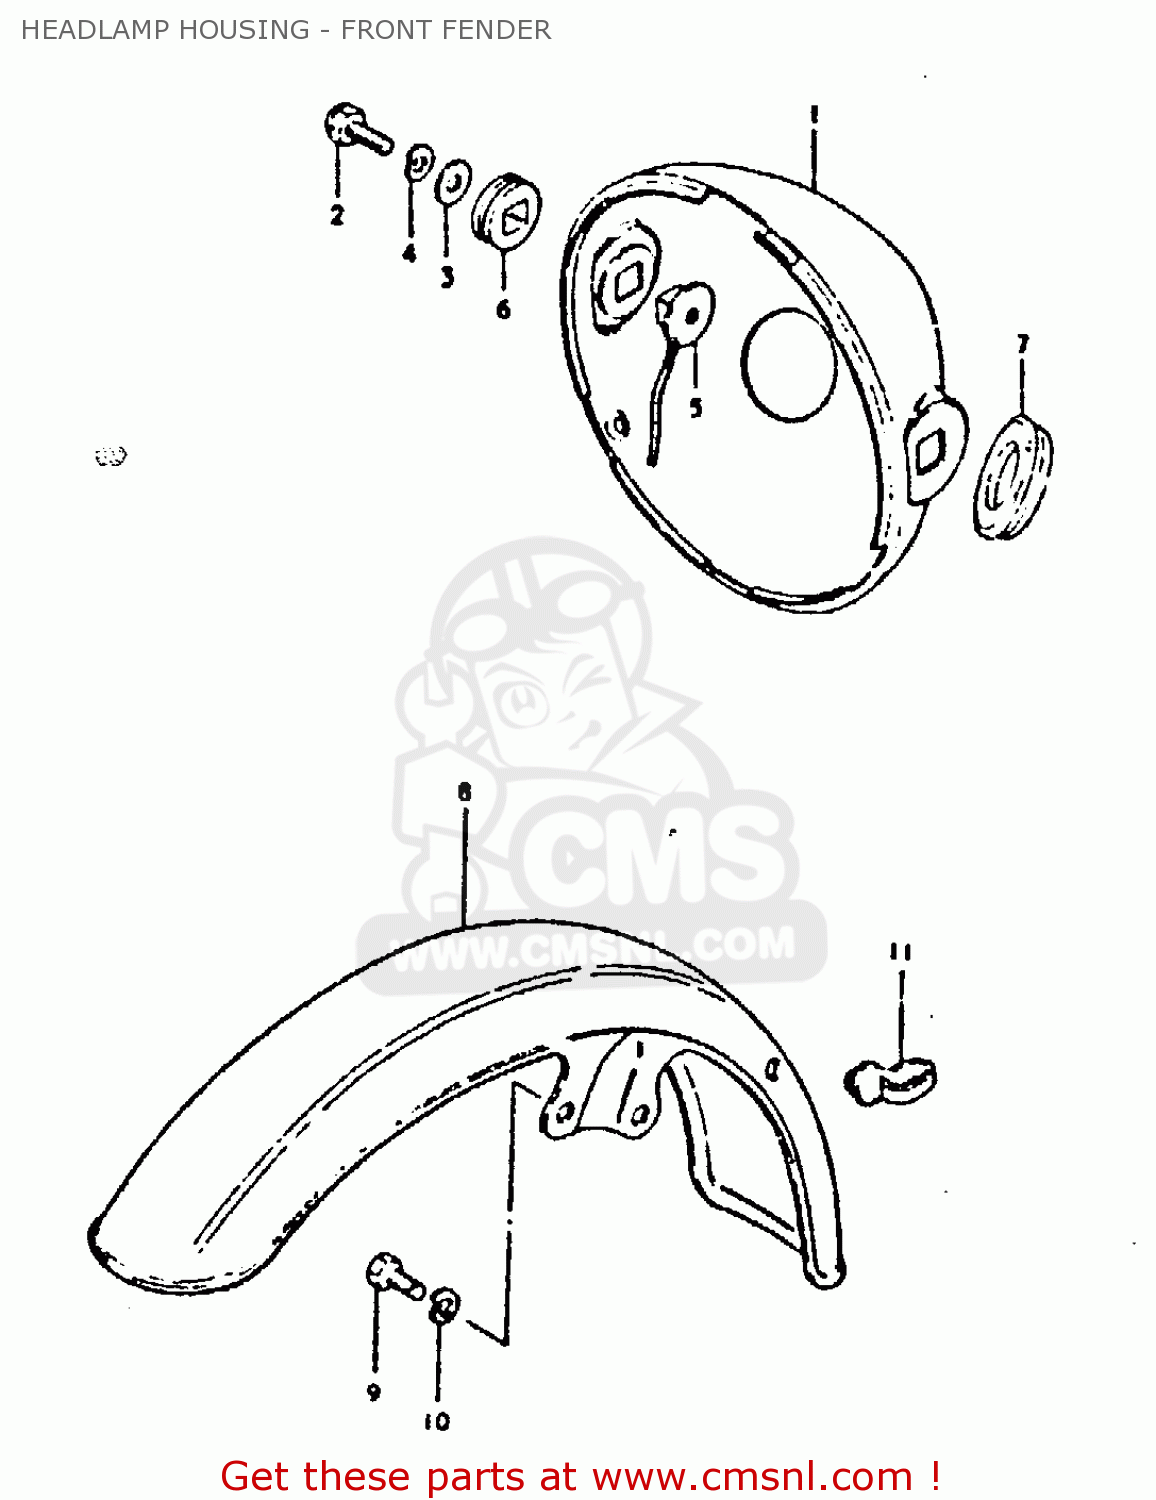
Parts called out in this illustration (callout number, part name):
1	HOUSING COMP,HEADLAMP
2	BOLT
3	WASHER
4	LOCK WASHER
5	SPACER,HEADLAMP HOUSING
6	CUSHION,HEADLAMP HOUSING
7	GROMMET,HEADLAMP HOUSING
8	FENDER,FR
9	BOLT
10	LOCK WASHER
11	GUIDE,CABLE
